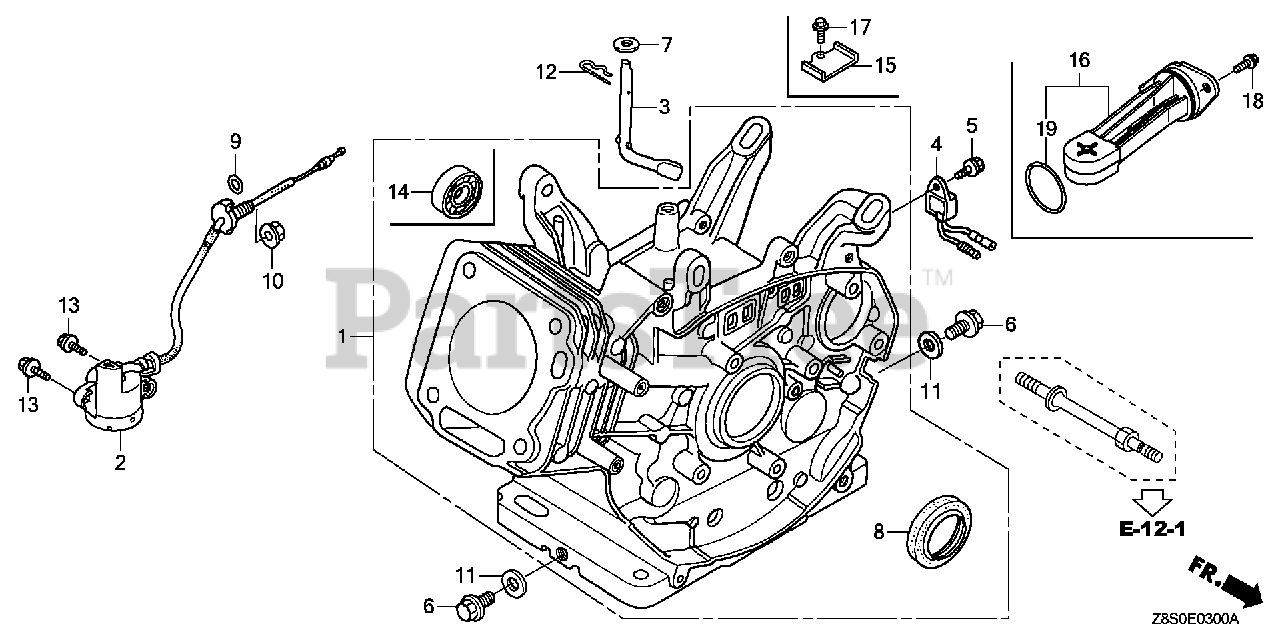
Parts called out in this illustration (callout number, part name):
1	CYLINDER ASSY.
6	BOLT, DRAIN PLUG (12X15)
8	OIL SEAL (30X46X8) (NOK ASIA)
11	WASHER, DRAIN PLUG (12MM)
14	BEARING, RADIAL BALL (6202)
15	BRACKET A, HARNESS
16	SWITCH ASSY., OIL LEVEL
17	BOLT, FLANGE (6X12) (CT200)
18	BOLT, FLANGE (6X16) (CT200)
19	O-RING (37.9X2.4)
